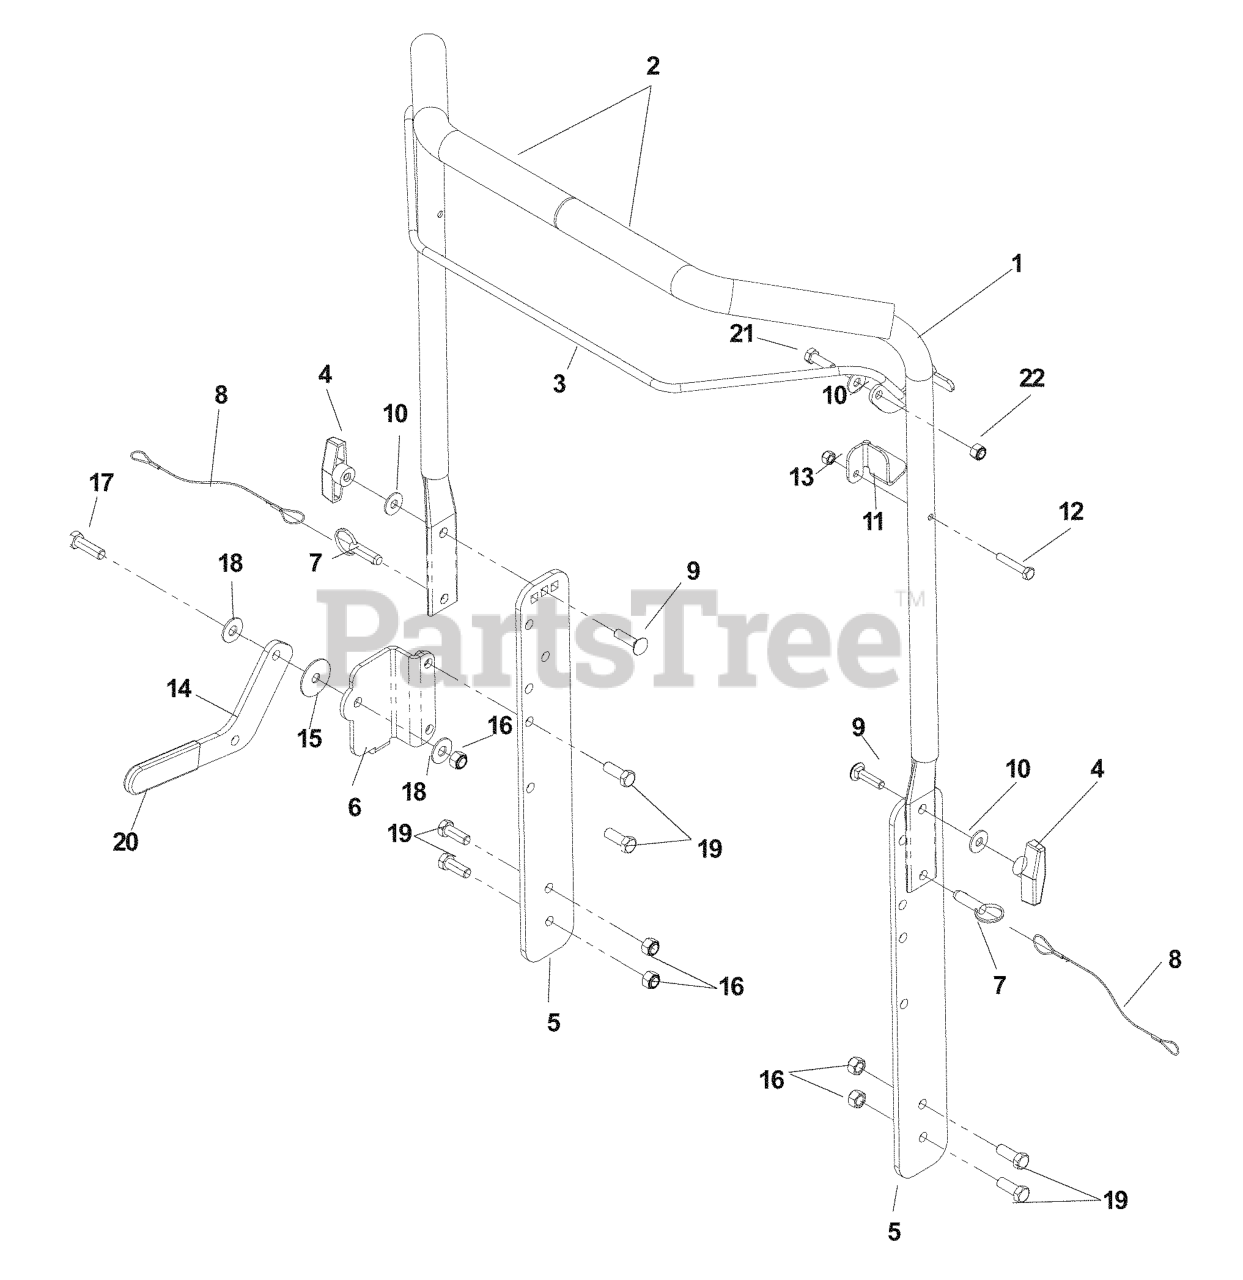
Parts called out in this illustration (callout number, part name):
1	HANDLE GRAY
3	BAIL - ORANGE
5	HANDLE SIDE GRAY
7	DETENT PIN RAKE/DT
9	BOLT, CARRIAGE 5/16X1-1/4
10	WASHER 5/16 FLAT
11	CABLE TAB POWER RAKE
12	SCW 1/4-20 X 1-1/2 HEX
13	NUT.1/4-20.HEX.NYLOC.ZD
15	WASHER, FRICTION
16	NUT 3/8-16 NYLOC
17	HCS 3/8C X 1 1/4 GR5
18	WASHER 3/8 FLAT
19	HCS 3/8-16X1.GRD.5.ZD
21	HCS 5/16C X 1
22	NUT 5/16 NYLOC
